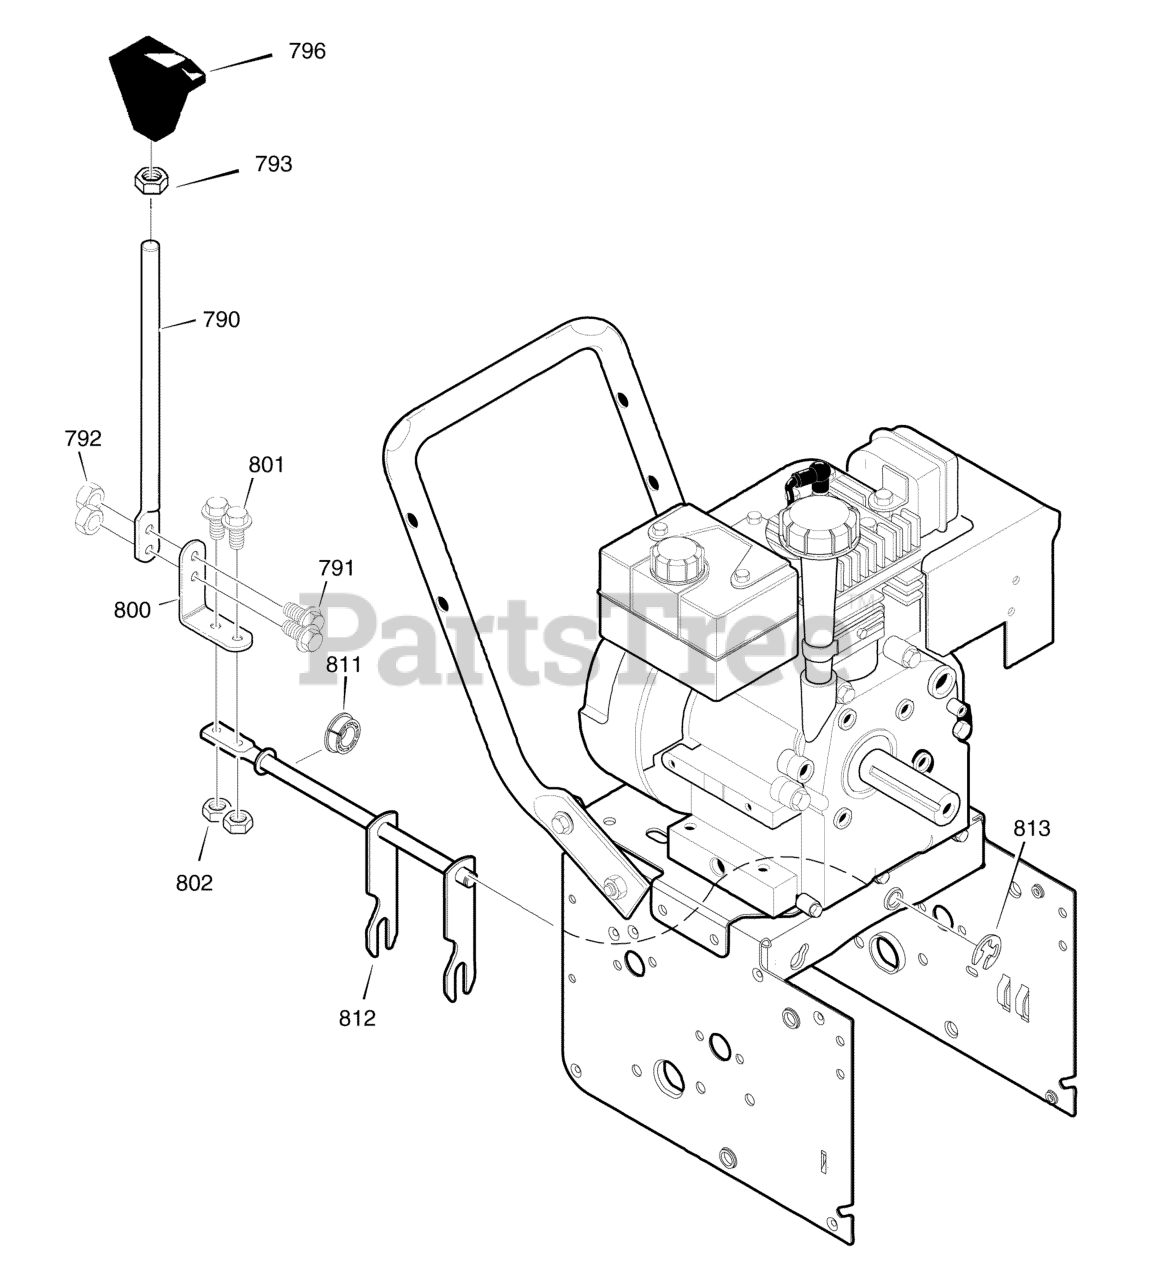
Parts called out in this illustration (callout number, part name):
790	ROD, SHIFT
791	SCREW, 1/4-20 X 0.75
792	NUT, 1/4-20
793	NUT, JAM
800	LEVER, SPRING
801	SCREW, 1/4-20 X 0.75
802	NUT, 1/4-20
811	BEARING, FLANGED
812	ROD ASSEMBLY, SPEED SELECT
813	RETAINER, RING
